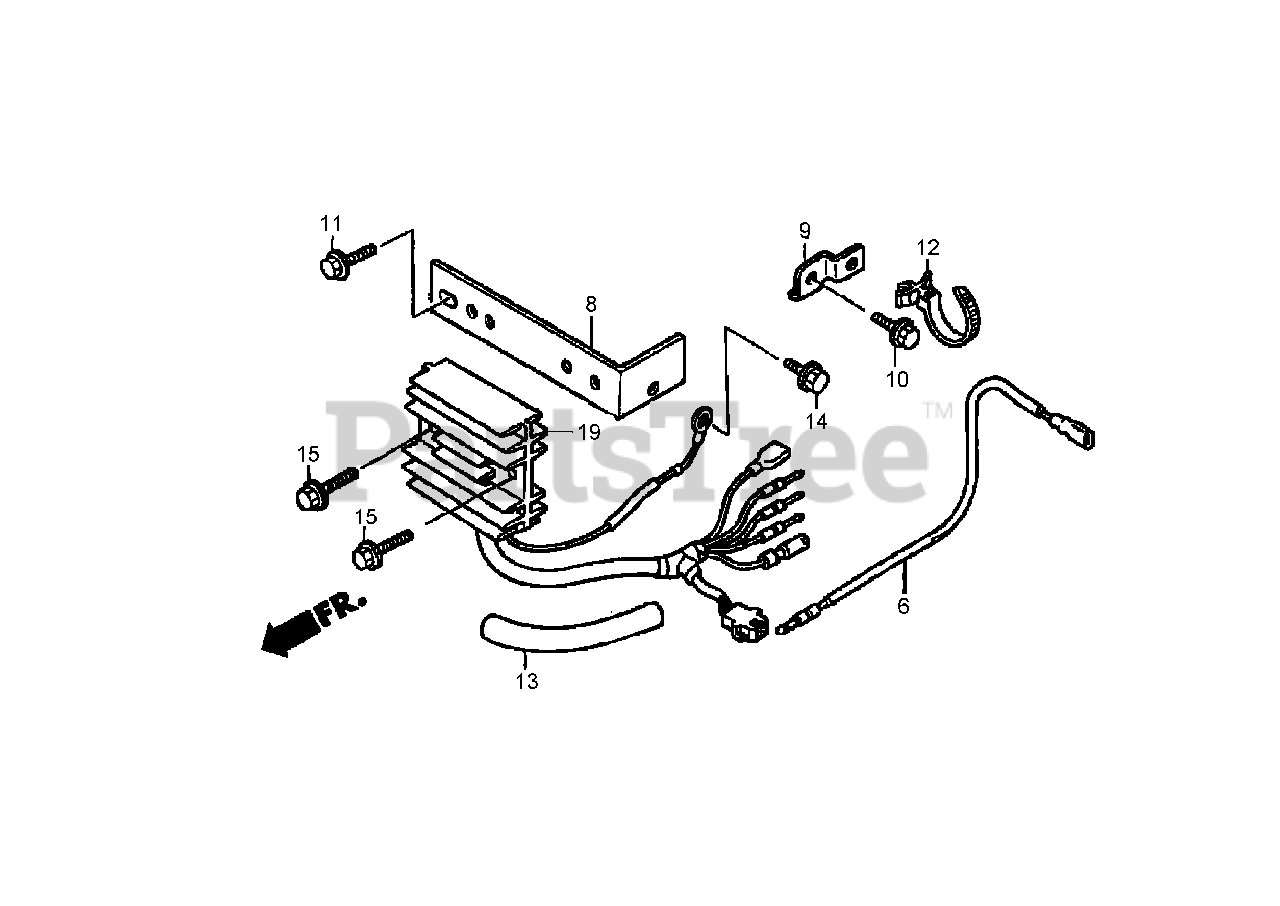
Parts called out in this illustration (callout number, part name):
6	SUB-WIRE HARNESS ASM
8	BRACKET-REGULATOR
9	BASE-CLIP
10	BOLT-FLANGE (6X12) (C T200)
11	BOLT-FLANGE (6X14) (C T200)
12	STRAP-CABLE (105MM) (N H1 BLACK)
13	TUBE-WIRE
14	BOLT-FLANGE (6X8)
15	BOLT-FLANGE (6X20)
19	REGULATOR RECTIFIER ASM
